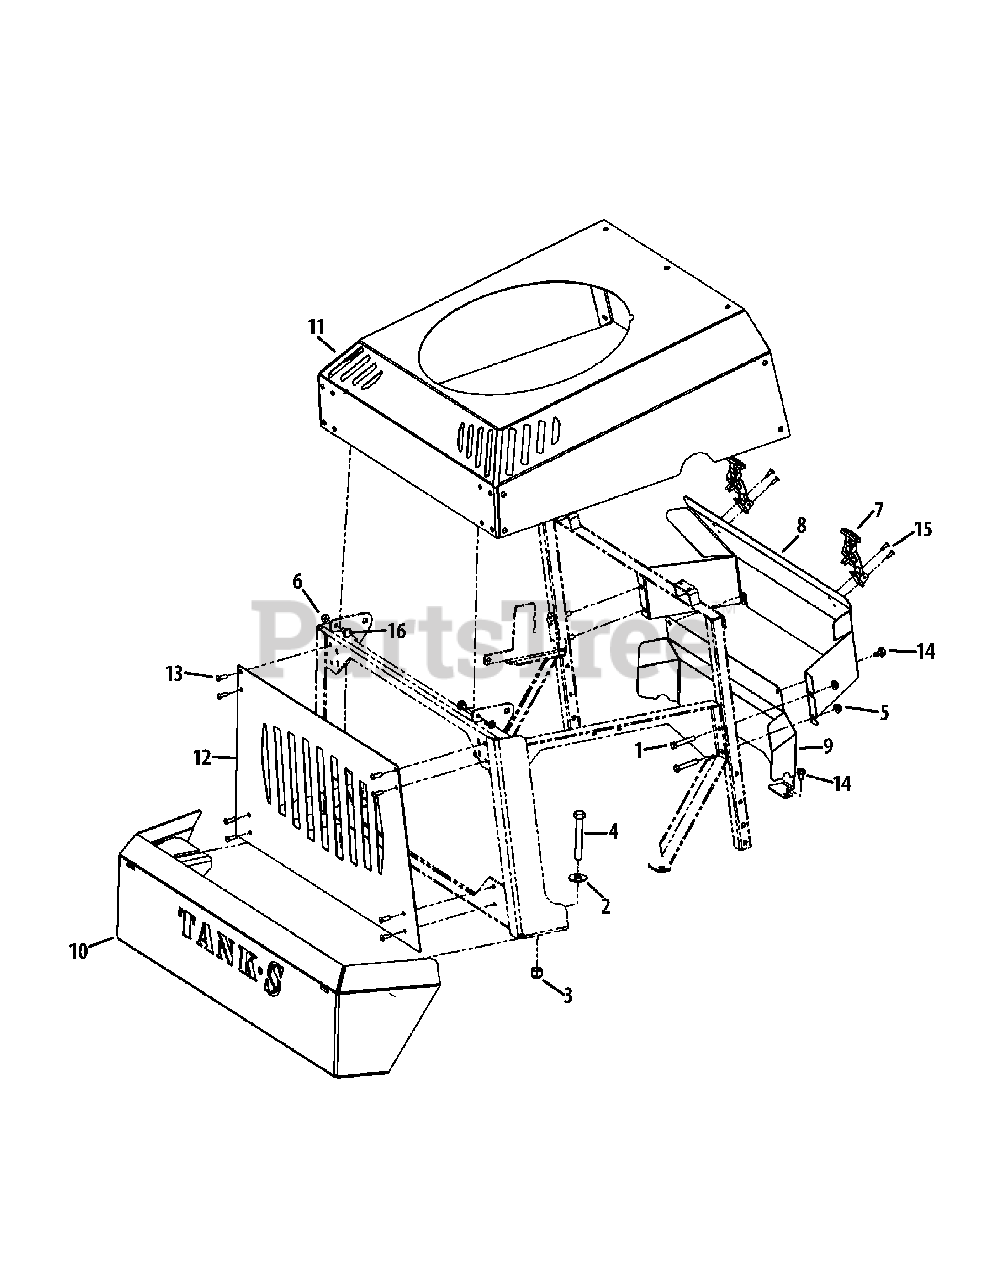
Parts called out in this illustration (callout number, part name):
1	Hex Screw, 5/16-18 x 1.75
2	Washer, .563 x 1.38 x .109
3	Nut, 1/2-13
4	Hex Screw, 1/2-13 x 3.50
5	Flange Counter Lock Nut, 5/16-18
6	Flange Top Luck Nut, 1/4-20
7	T-Handle Draw Latch
8	Top Guard Plate
9	Front Bottom Guard Plate
10	Bumper Assembly
11	Hood Assembly
13	Machine Screw, 1/4-20 x 0.750
14	Hex Washer Screw, 5/16-18 x 0.625
15	Rivet, 3/16
16	Shoulder Screw, .375 x .181
